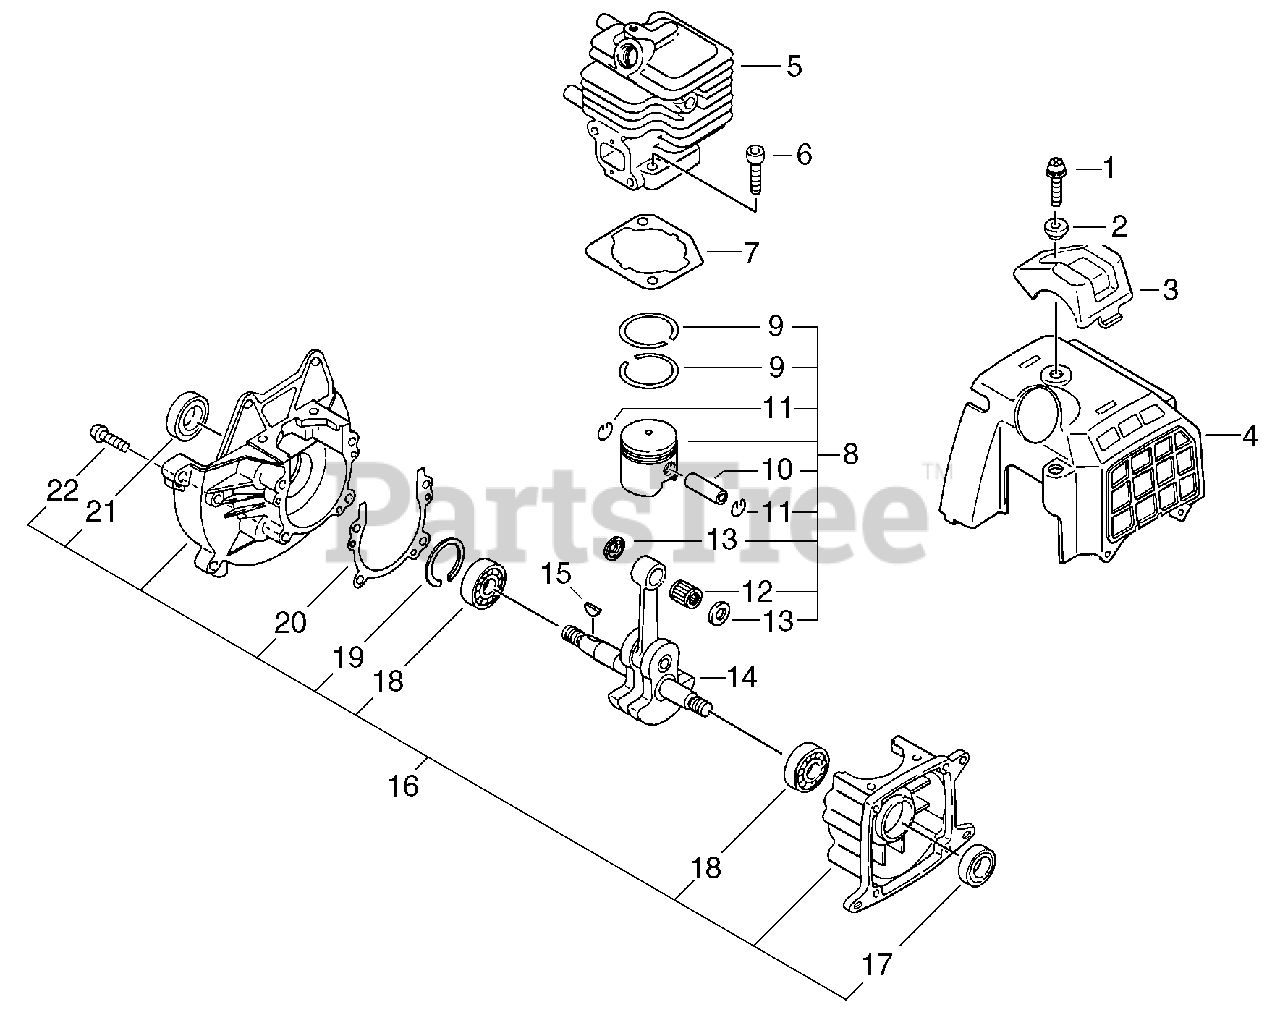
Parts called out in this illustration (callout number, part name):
1	BOLT, FLANGE
2	COLLAR 5
3	GUARD, TOP
4	COVER, ENGINE
5	CYLINDER
6	BOLT 5×22
7	GASKET, CYLINDER
8	PISTON KIT
9	RING, PISTON
10	PIN, PISTON
11	RING, SNAP
12	BEARING, NEEDLE 8
13	WASHER, THRUST
14	CRANKSHAFT ASSY
15	KEY, WOODRUFF
16	CRANKCASE KIT
17	SEAL, OIL 12
18	BEARING, BALL 6001
19	RING, SNAP 28
20	GASKET, CRANKCASE
21	SEAL, OIL 12
22	BOLT 5×25
